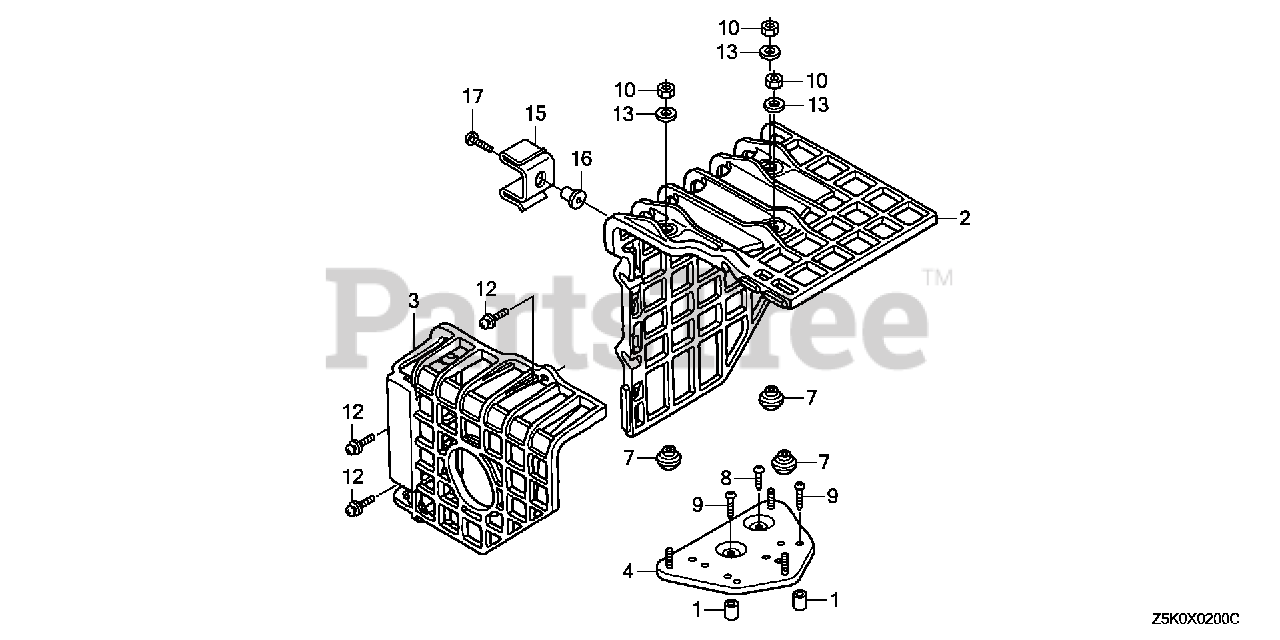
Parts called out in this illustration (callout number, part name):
1	COLLAR, AIR CLEANER HOUSING
2	COVER, MUFFLER
3	COVER, RR. MUFFLER
4	BASE, MUFFLER COVER
7	SPACER, MUFFLER COVER
8	SCREW, TAPPING (5X8)
9	SCREW, TAPPING (5X25)
10	NUT, HEX. (5MM)
12	SCREW-WASHER (6X20)
13	WASHER, PLAIN (5MM)
15	STAY, MUFFLER COVER
16	COLLAR, FAN COVER
17	SCREW, TAPPING (6X25)
